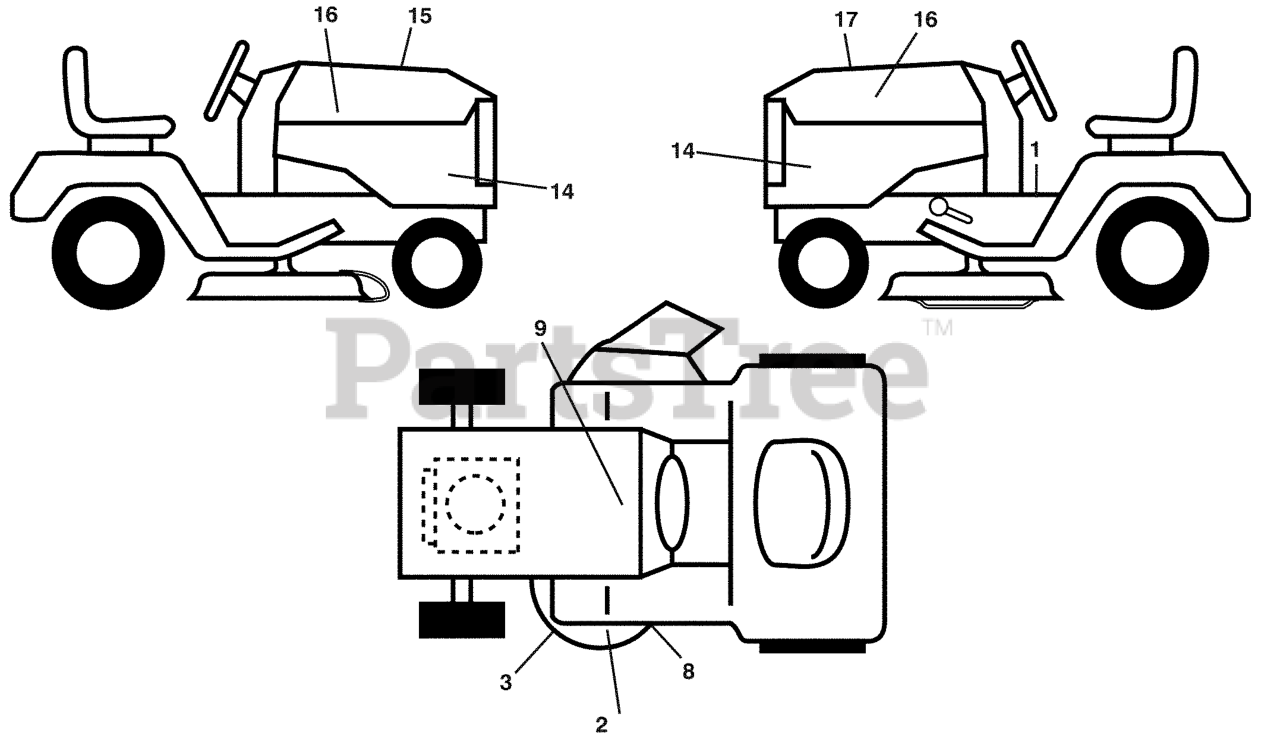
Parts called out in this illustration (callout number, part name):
1	DECAL.FENDER.WARNING.ENG
2	DECAL.DECK.AIR.INDUCTION.HUSQ
3	DECAL.WARN.KEEP.HAND.AWAY
8	DECAL.MOWER.SCH.48/54
9	DECAL BTRY SYMBOLS
14	DECAL.PNL.SD.2754GXLS.
15	DECAL.WARNING.CUST.RESP.E85.
16	RP EMBLEM, HOOD
